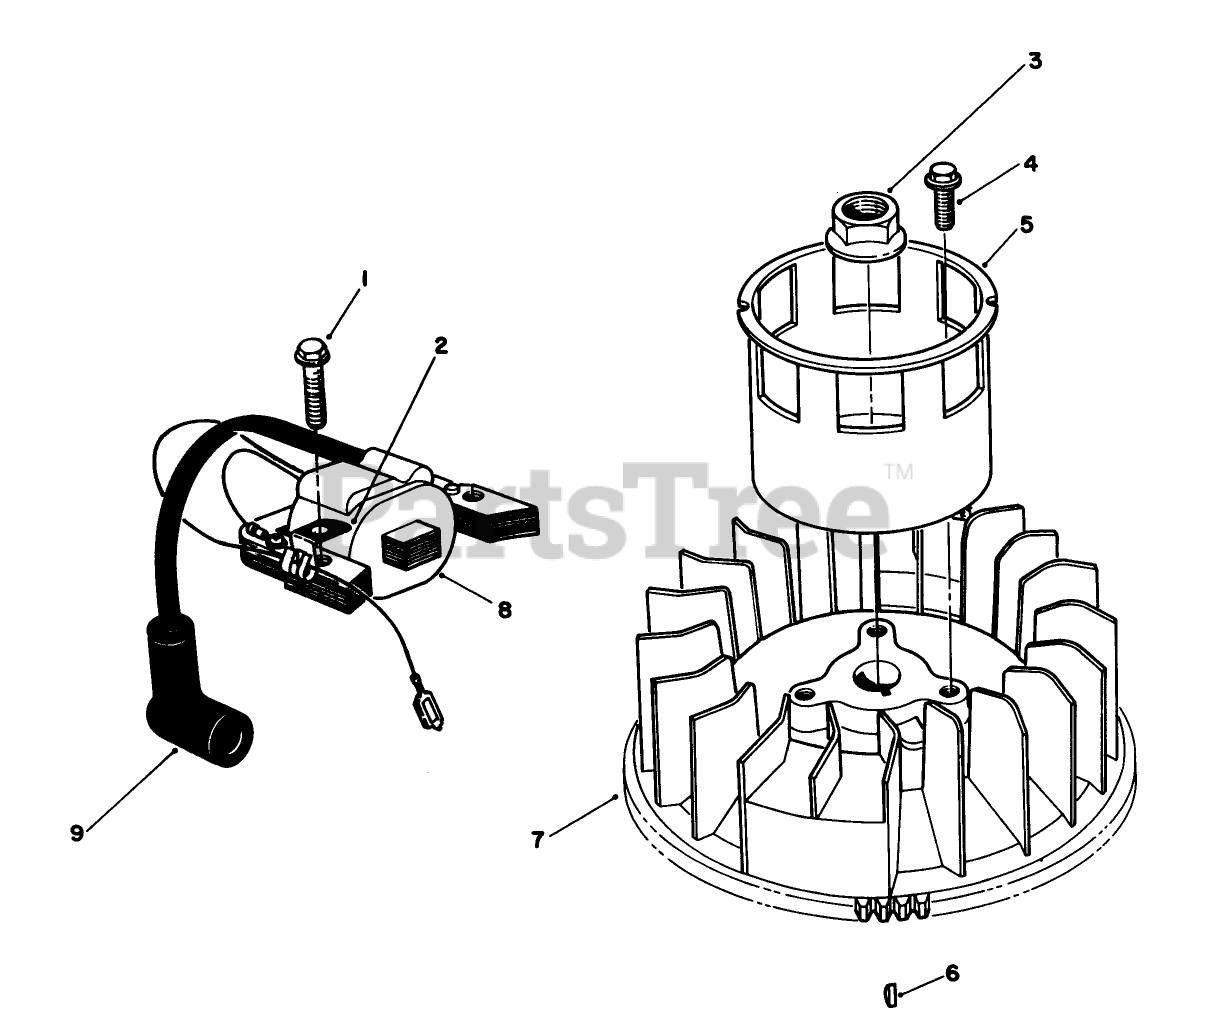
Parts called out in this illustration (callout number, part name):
2	CLAMP
7	FLYWHEEL
8	COIL ASM
9	COVER
